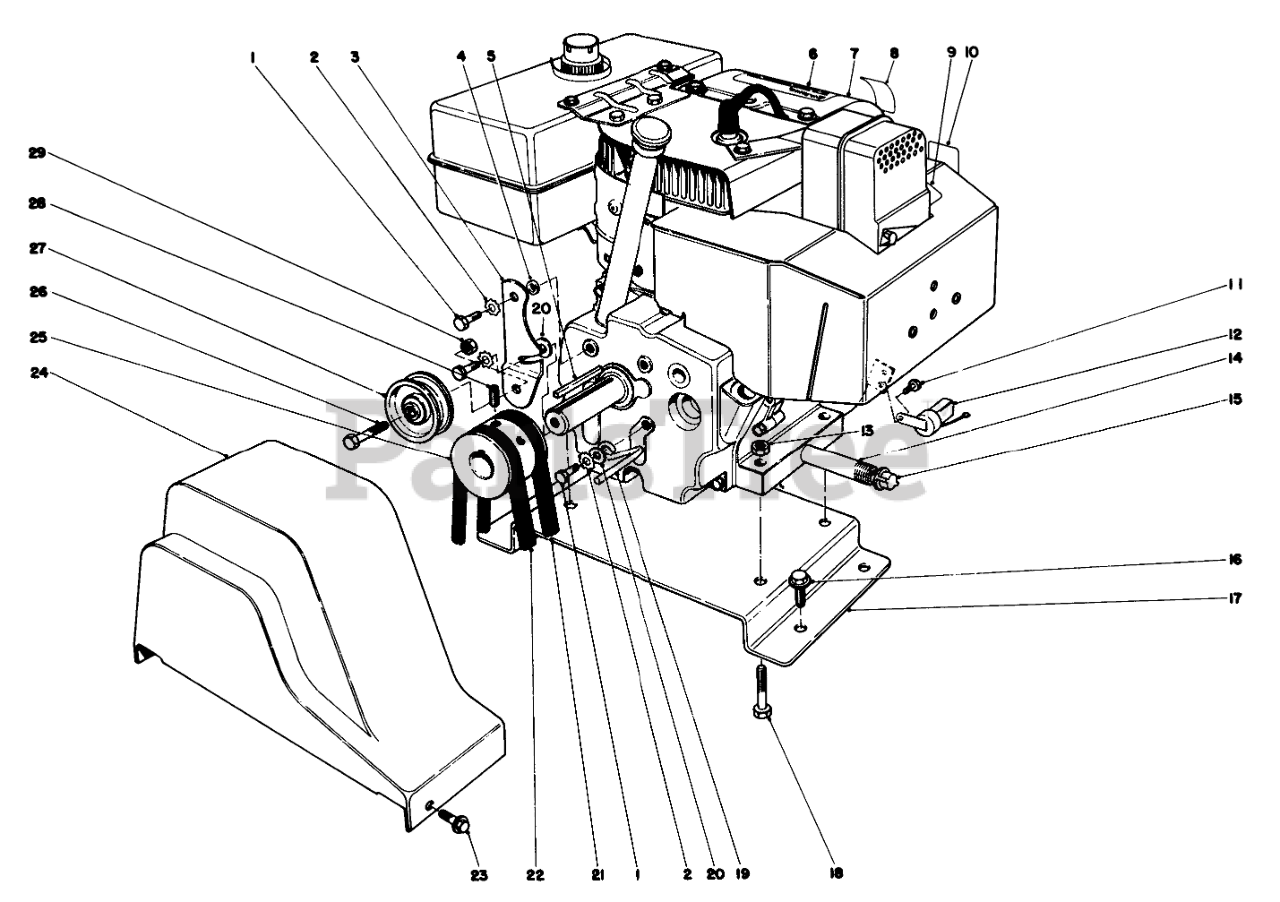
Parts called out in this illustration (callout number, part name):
1	SCREW-HH
2	WASHER-LOCK
3	ENGINE IDLER ARM
4	SPACER
6	Decal-Hazard
7	Engine
8	PRIMER DECAL
9	Decal Hot Surface Warning
10	CHOKE DECAL
11	SCREW
12	INTERLOCK MODULE
13	NUT-LOCK, NI
14	NIPPLE-PIPE
15	CAP-PIPE
16	SCREW-HHFTF
17	Plate ngine Mounting
18	SCREW-HH
19	BELT RETAINER
20	WASHER-PLAIN
21	V-BELT
22	V-BELT
23	SCREW-HWH
24	BELT GUARD
25	ENGINE PULLEY
26	SCREW-HH
27	PULLEY-IDLER
28	Screw-Set
29	NUT-HEX
